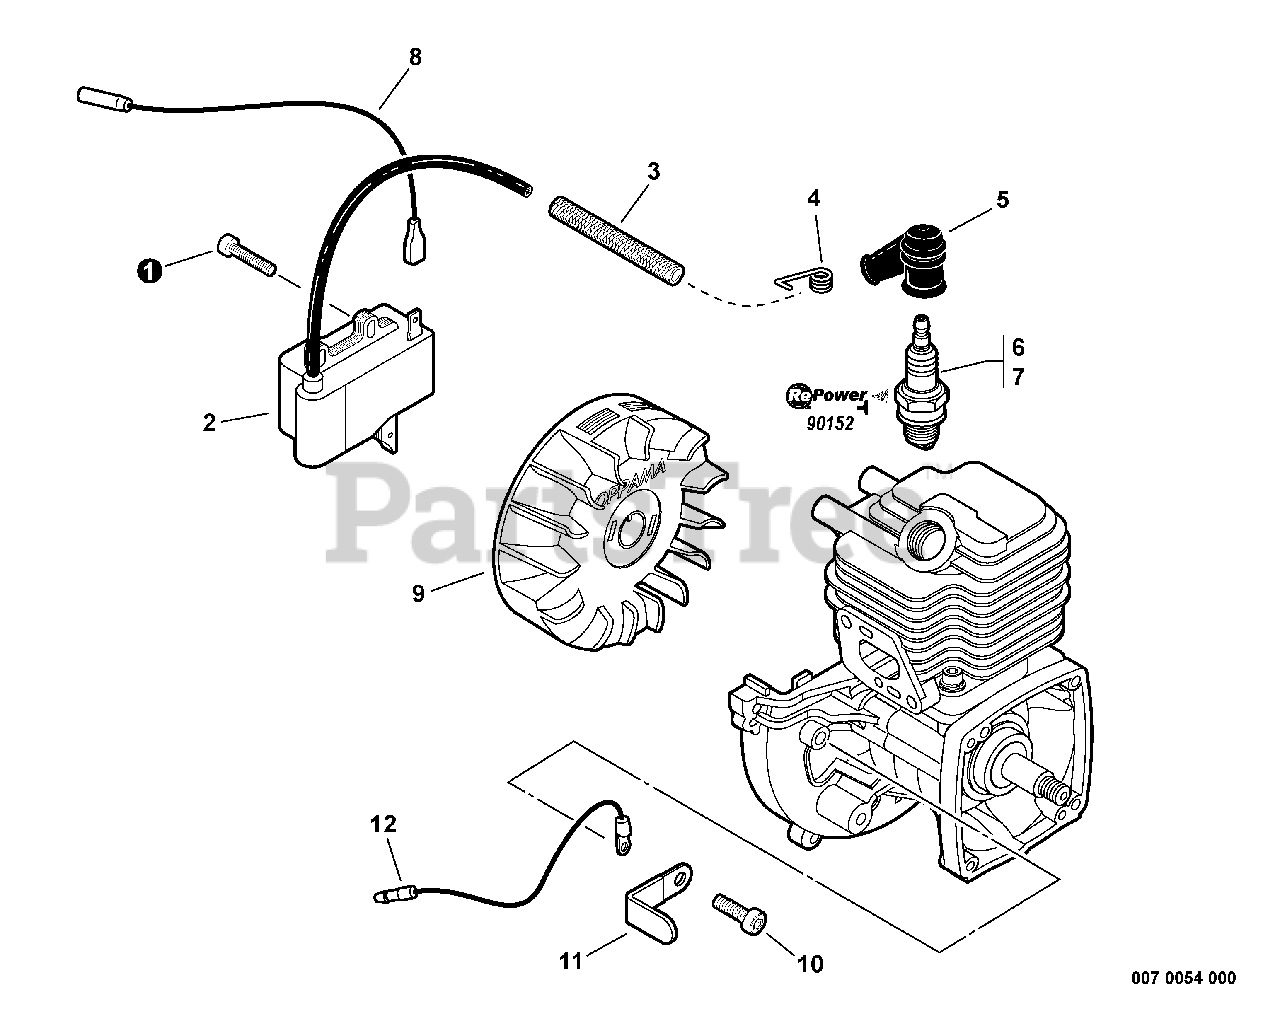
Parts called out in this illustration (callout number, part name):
1	SCREW - 4X20
2	COIL, IGNITION
3	TUBE, INSULATOR
4	TERMINAL, SPARK PLUG CAP
5	CAP, SPARK PLUG
6	SPARK PLUG -- BPM-8Y
7	SPARK PLUG -- BPMR-8Y
8	LEAD - IGNITION
9	FLYWHEEL
10	SCREW - 5X10
12	LEAD - GROUND
TU	RePower TUNE-UP KIT
